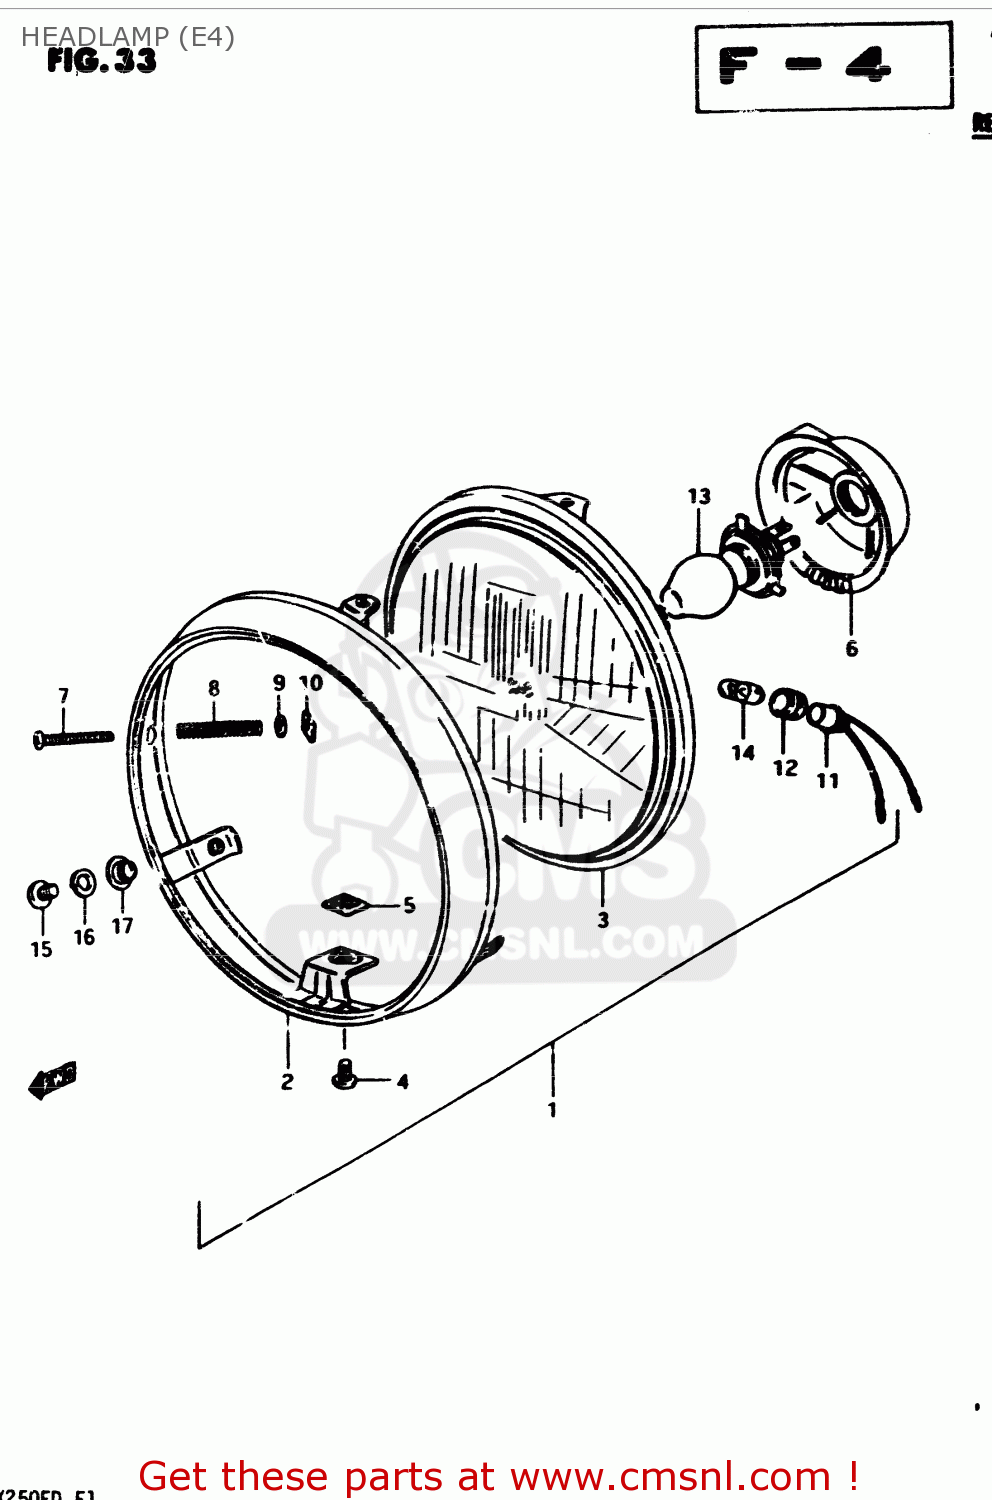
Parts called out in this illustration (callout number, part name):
1	HEADLAMP ASSY
2	RIM
3	LAMP UNIT
4	SCREW
5	NUT,ADJUSTING
6	COVER,SOCKET
7	SCREW,HEADLAMP ADJUST
8	SPRING
9	WASHER
10	NUT,HEADLAMP ADJUSTER
11	SOCKET
12	JOINT,RUBBER
13	BULB (12V, 60/55W, H4)
14	BULB(12V4W)
15	SCREW
16	WASHER,LOCK
17	WASHER
